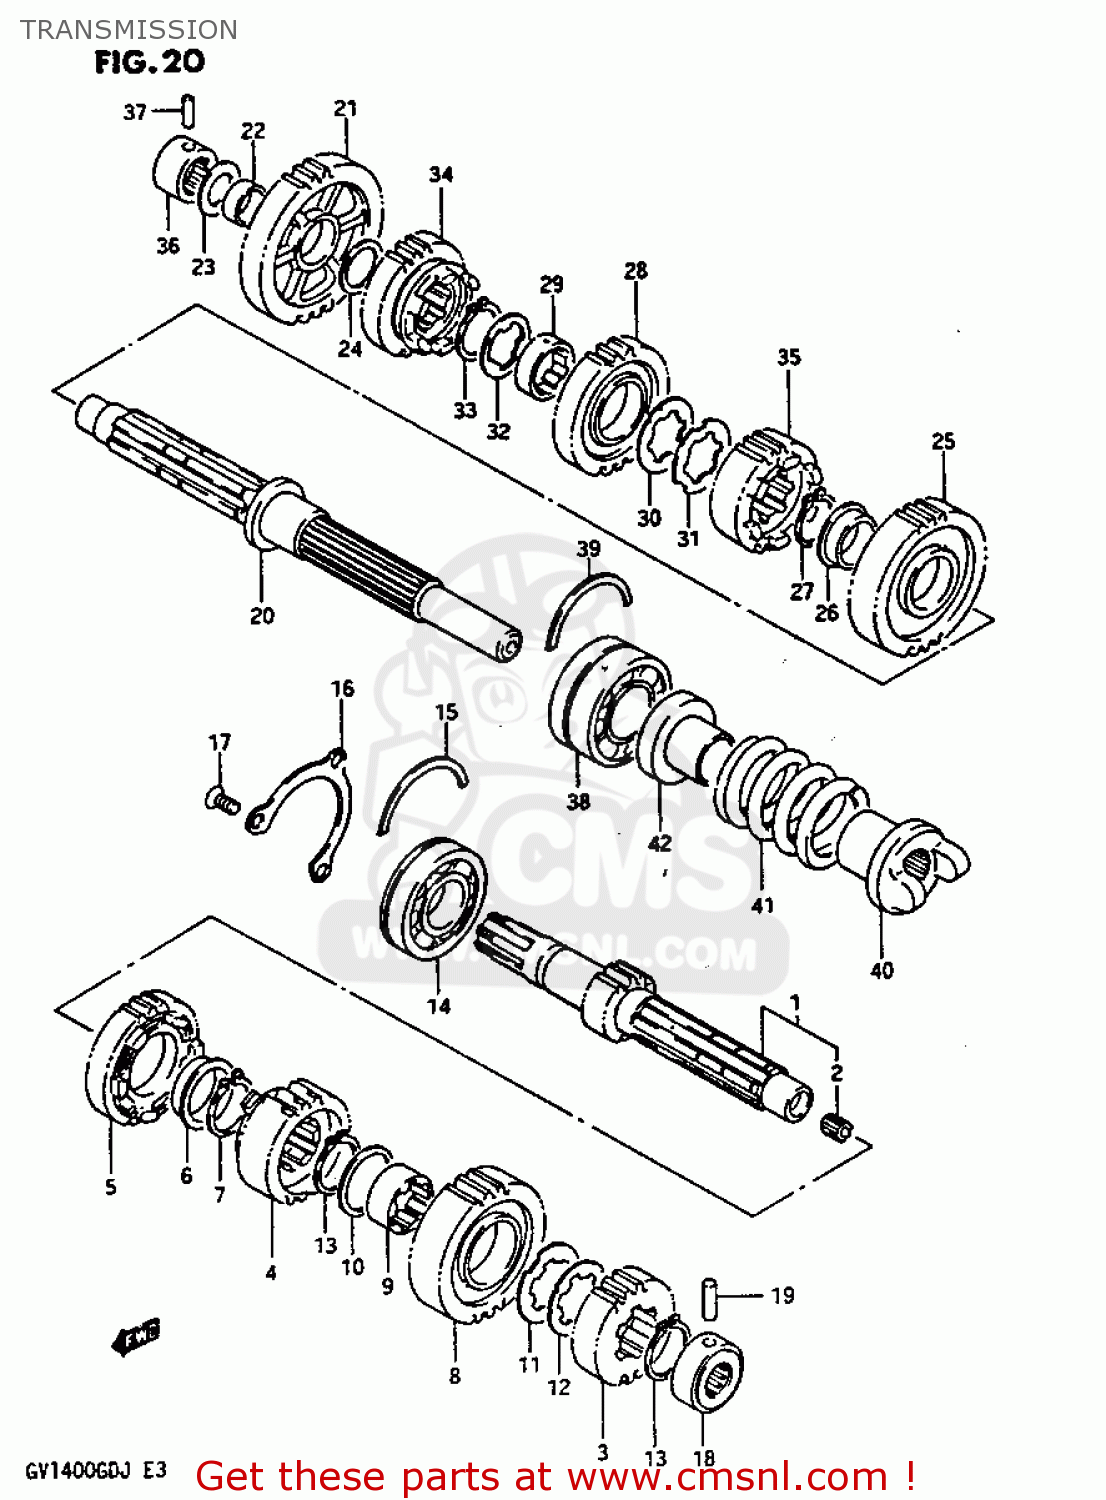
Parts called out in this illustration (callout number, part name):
1	SHAFT,COUNTER
2	BUSH
3	GEAR,SECOND DRIVE
4	GEAR,THIRD DRIVE
5	GEAR,FOURTH DRIVE
6	BUSH(28X32X2)
7	CIRCLIP
8	GEAR,FIFTH DRIVE
9	BUSH
10	WASHER,LOCK
11	WASHER,LOCK
12	WASHER,LOCK
13	CIRCLIP
14	BEARING(25X62X17)
15	C-RING
16	PLATE,COUNTERSHAFT BEARING
17	SCREW
18	ROLLER BEARING (20X36X1
19	PIN
20	SHAFT,DRIVE
21	GEAR,FIRST DRIVEN
22	BUSHING
23	WASHER
24	WASHER
25	GEAR,SECOND DRIVEN
26	BUSH(28X32X2)
27	CIRCLIP
28	GEAR,THIRD DRIVEN
29	BUSH,3RD DRIVEN GEAR
30	WASHER
31	WASHER,LOCK
32	WASHER,LOCK
33	CIRCLIP
34	GEAR,FOURTH DRIVEN
35	GEAR,FIFTH DRIVEN
36	BEARING(20X34X20)
37	PIN
38	BALL BEARING 30X62X28
39	C-RING
40	DOG,INPUT CAM
41	SPRING
42	STOPPER,CAM SPRING
